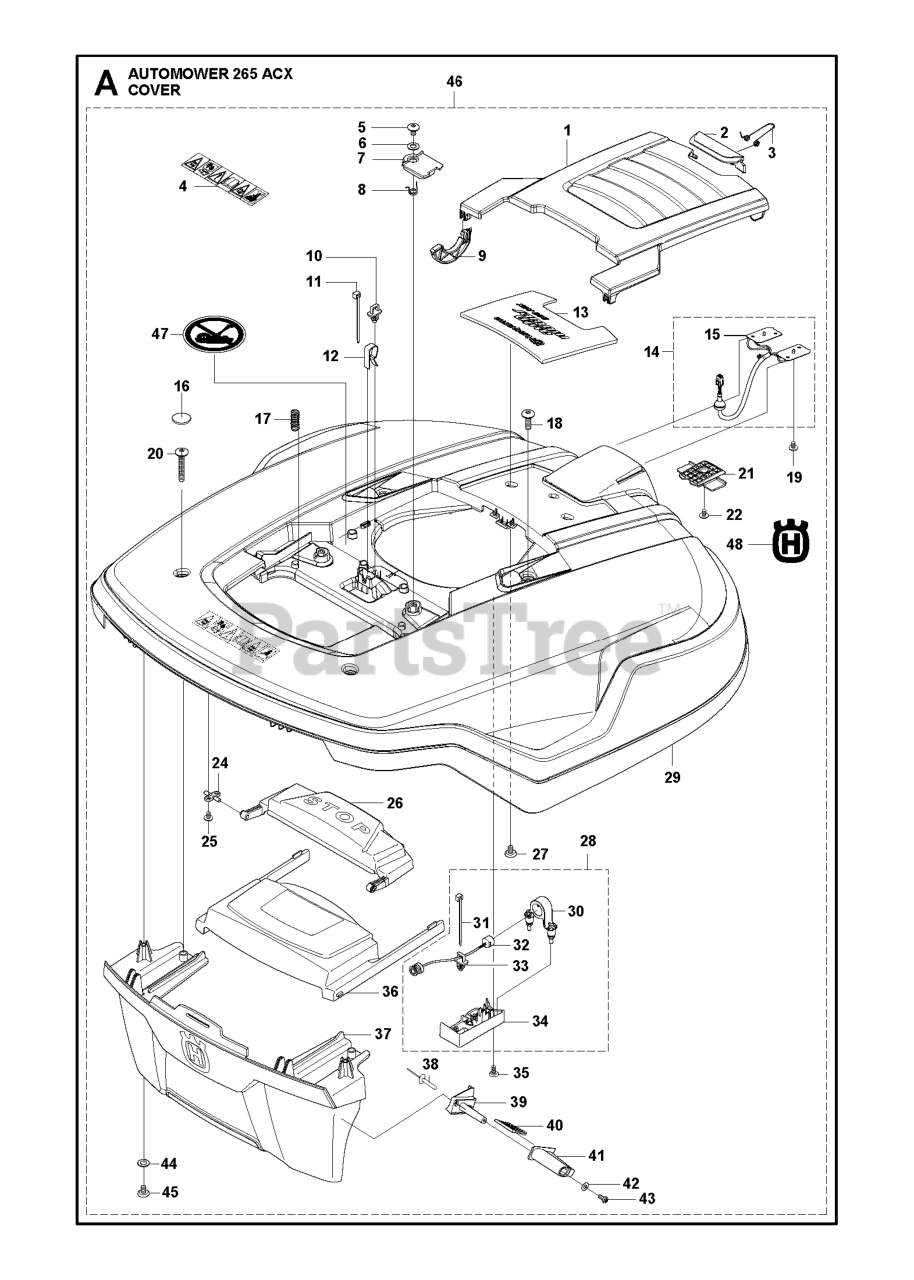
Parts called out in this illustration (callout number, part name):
4	LABEL WARNING
5	SCREW SILVER 10MM
10	BRACKET FOR BAND
12	CLIP RETAINER
15	THIN PLATE
18	SCREW IHPANM M6X25 4.6 ZP-BC
19	SCREW WHITE 6MM
22	SCREW 12MM
25	SCREW SILVER 10MM
27	SCREW 12MM
33	BRACKET FOR BAND
35	SCREW 14MM
43	SCREW 14MM
47	LABEL WARNING KIT 10 PCS
48	DECAL HUSQVARNA CROWN HEIGHT 5
